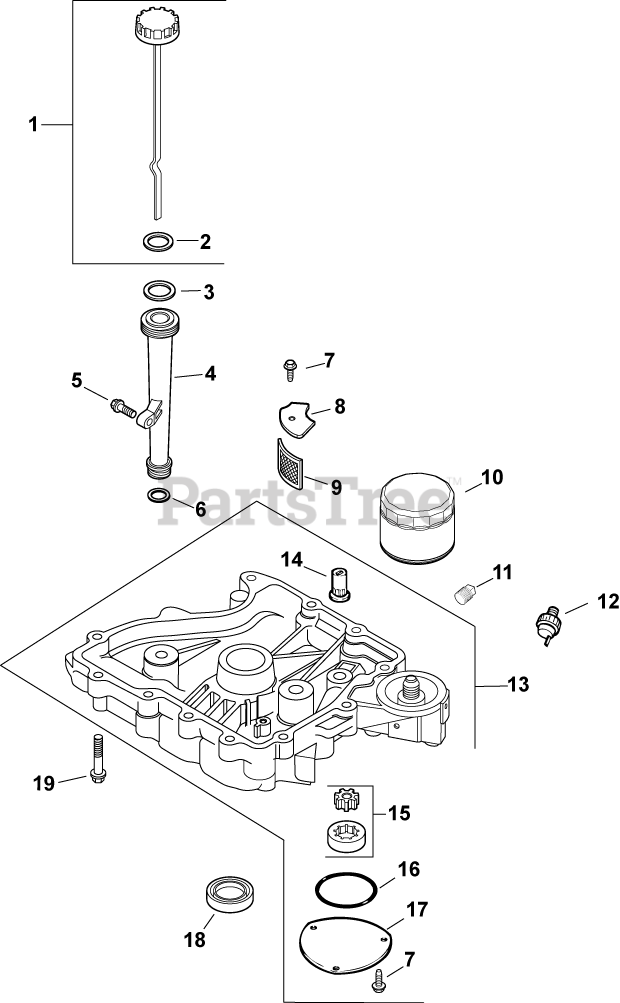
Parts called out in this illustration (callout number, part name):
1	DIPSTICK/CAP ASSY (BLACK)
2	O-RING, DIPSTICK
3	O-RING, DIPSTICK
4	TUBE, OIL FILL USE 25 123 07-S
5	SCREW,FLG THD FRM M6X1.0X20-(#25086396S)
6	O-RING, LOWER OIL FILL TUBE
7	SCREW,FLG THD FRM M5X0.8X16-(#25086398S)
9	SCREEN, OIL-USE 24 162 26-S
10	OIL FILTER
11	PLUG, SQ HD PIPE 3/8"
12	SENSOR, OIL PSI
13	PAN, OIL
14	VALVE, OIL PRESSURE RELIEF
15	PUMP ASSEMBLY, OIL
16	O-RING (2.5" DIA)
17	COVER, OIL PUMP
18	SEAL, OIL
19	SCREW, FLG M8X1.25X45
